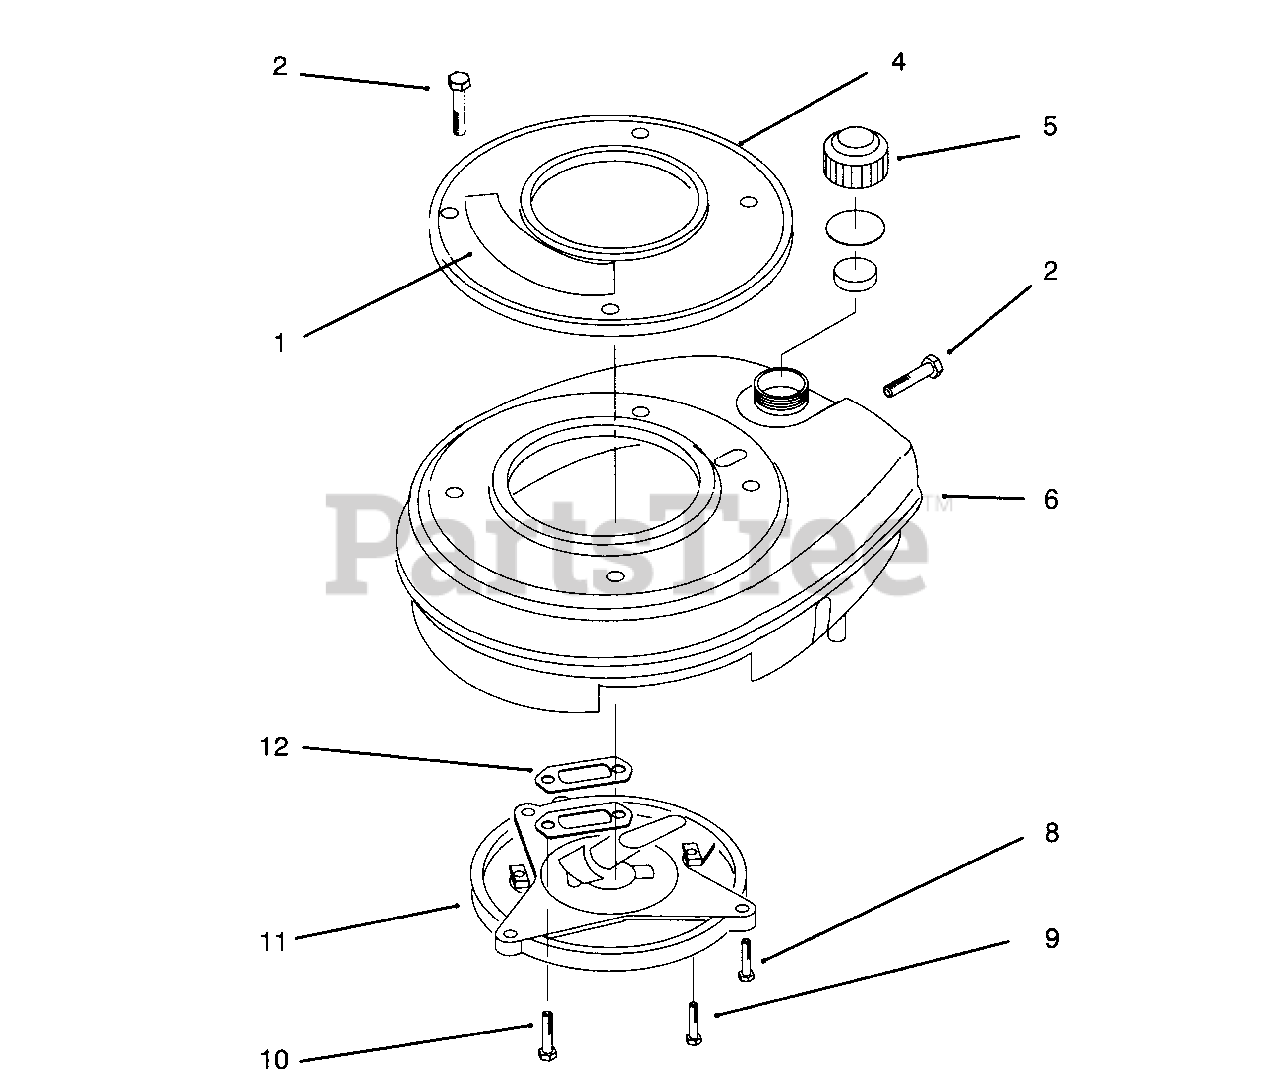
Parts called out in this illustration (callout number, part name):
1	Applique
2	Screw
4	StarterBase
5	Fuel Cap
6	Shroud-Engine
8	Screw-Muffler Plt. to Hsg.
9	Screw Muffler Plt. to Block
11	Plate-Muffler
12	Gasket-Exhaust
